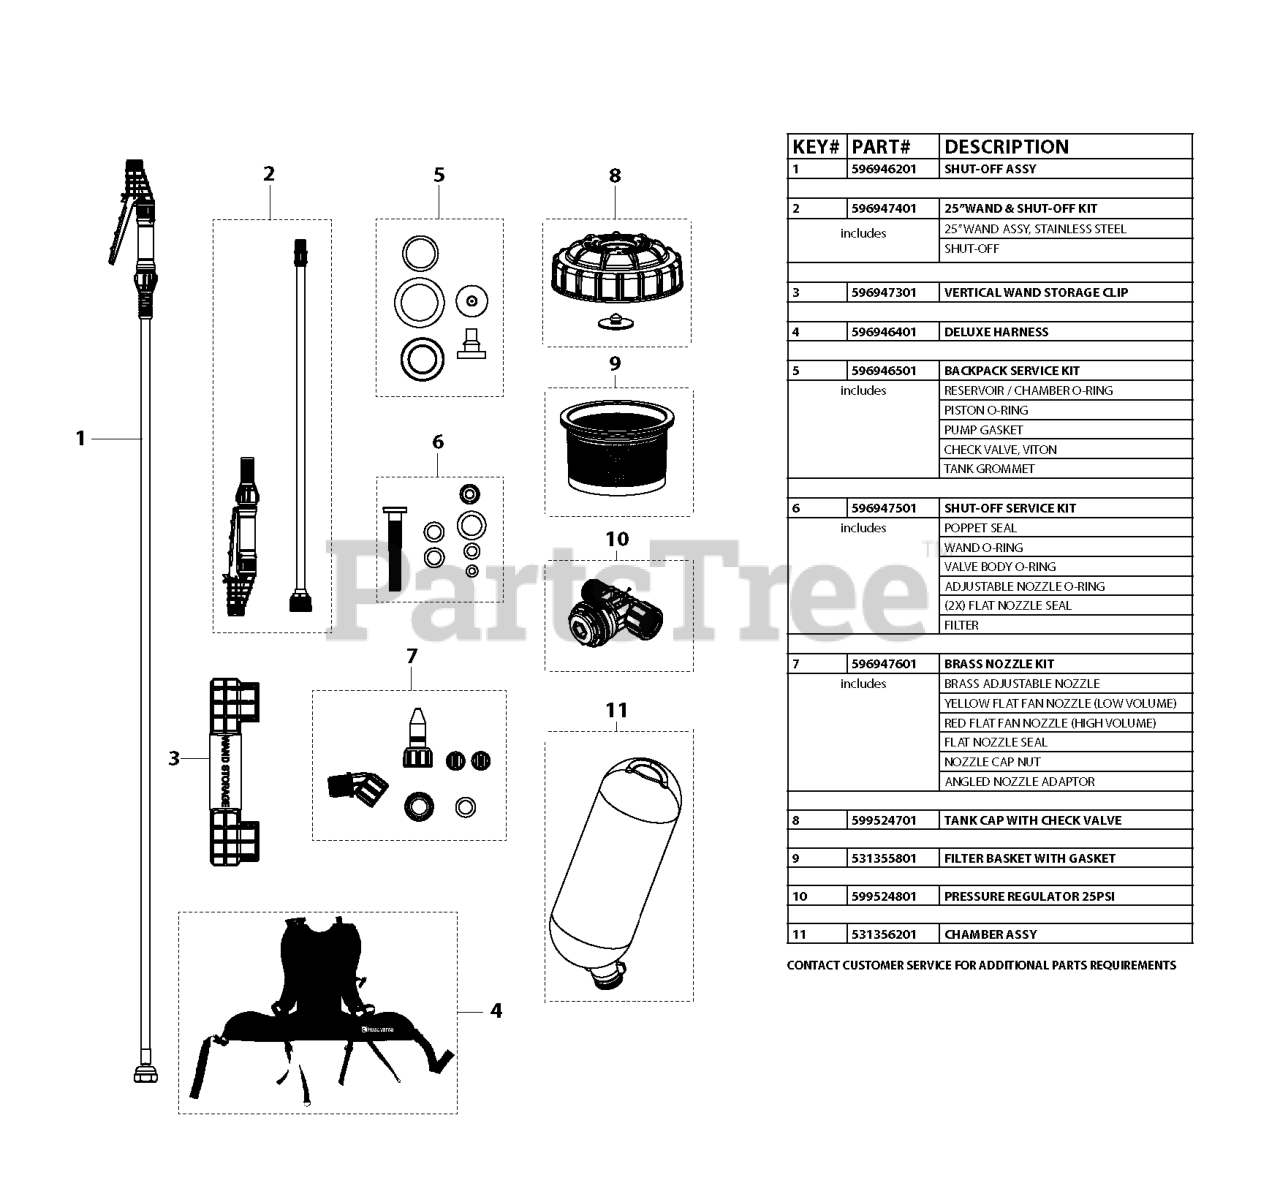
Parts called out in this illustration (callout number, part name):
1	4G SPRAYER SHUTOFF/HOSE ASSY
2	SPRAYER WAND/SHUTOFF KIT
3	4G SPRAYER WAND STORAGE CLIP
4	HUS 4G SPRAYER DELUXE HARNESS
5	4G SPRAYER O-RING KIT
6	SPRAYER SHUTOFF SERVICE KIT
7	SPRAYER NOZZLE KIT
8	Sprayers
10	Sprayers
